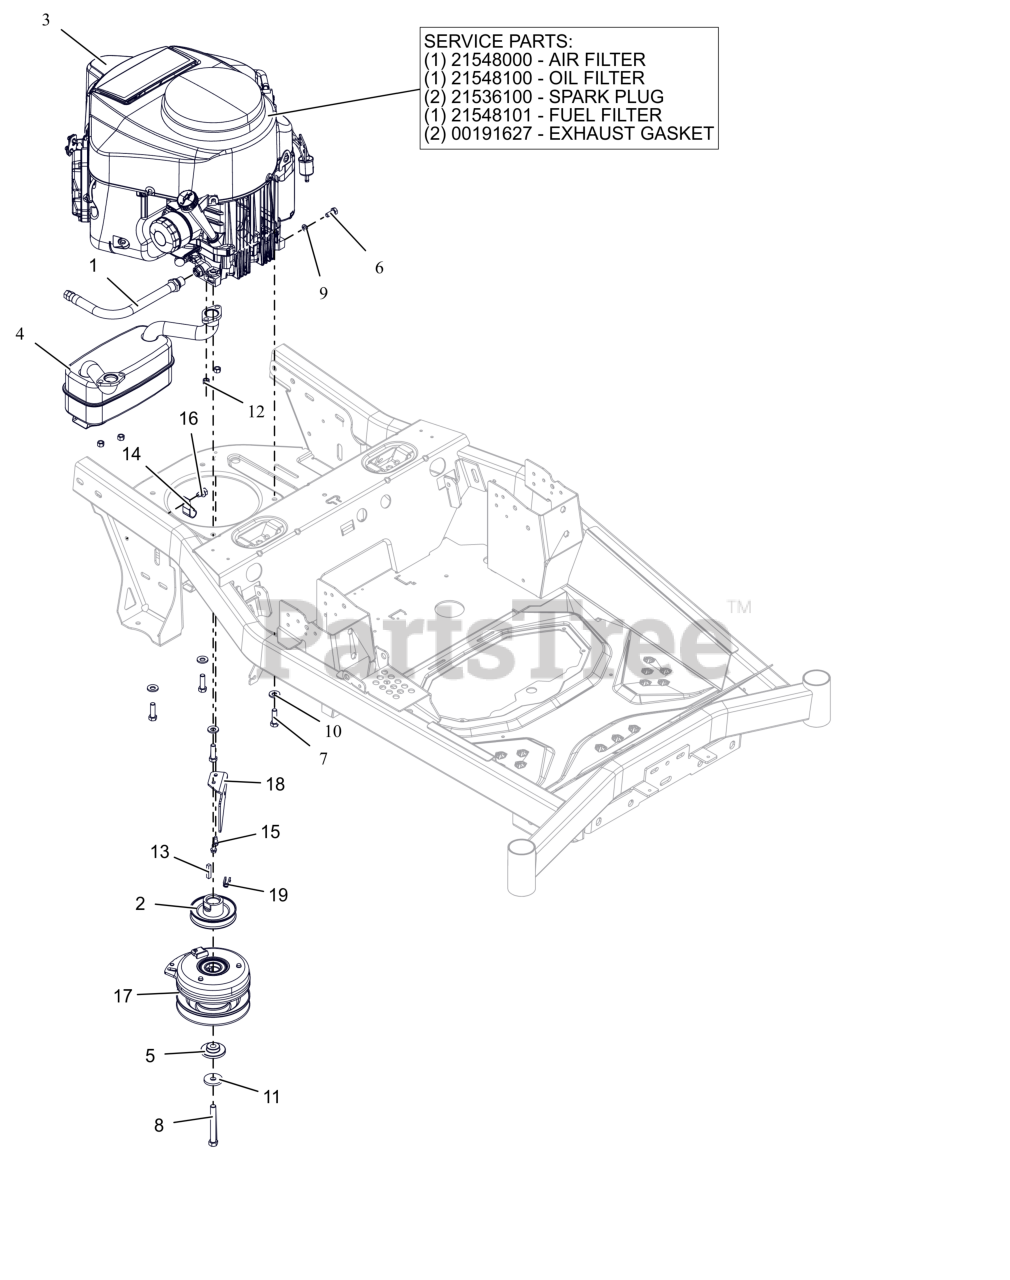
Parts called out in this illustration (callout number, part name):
1	HOSE, OIL DRAIN
2	WLDMT, PULLEY 3.75 OD X 1.003 ENGINE
3	ENGINE, KAWASAKI FR651V
3	AIR FILTER, KAWASAKI FR
3	OIL FILTER, KAWASAKI FR
3	PLUG, SPARK
3	FUEL FILTER-KAWASAKI FR
3	GASKET, MUFFLER S/O
4	MUFFLER - KAWASAKI
5	BSHG-FLG .469X1.06X.574X2.0
6	BLT, HEX M8-1.25X20 G8.8 ZCC
7	BLT, HEX .38-16X1.25 G5 ZCC NT
8	BLT, HEX 0.4375-20X3.5 G8 ZCC NT
9	WSHR,LK-REG .312X.078 ZCC
10	WASHER, 3/8" SPRING DISC
11	WASHER, 7/16" SPRING DISK
12	NUT-LK-TOP-FLG M8 ZCC
13	KEY-SQ .25 X 1.25 X .25 SAE
14	J-CLAMP
15	SCR-TAP .25-20X.50 HWH ZCC
16	SCR,TAP .375-16X.50 HWH TR ZCC
17	CLUTCH- WARNER IXR-18211
18	BRKT- CLUTCH STOP
19	BSHG, CLUTCH
